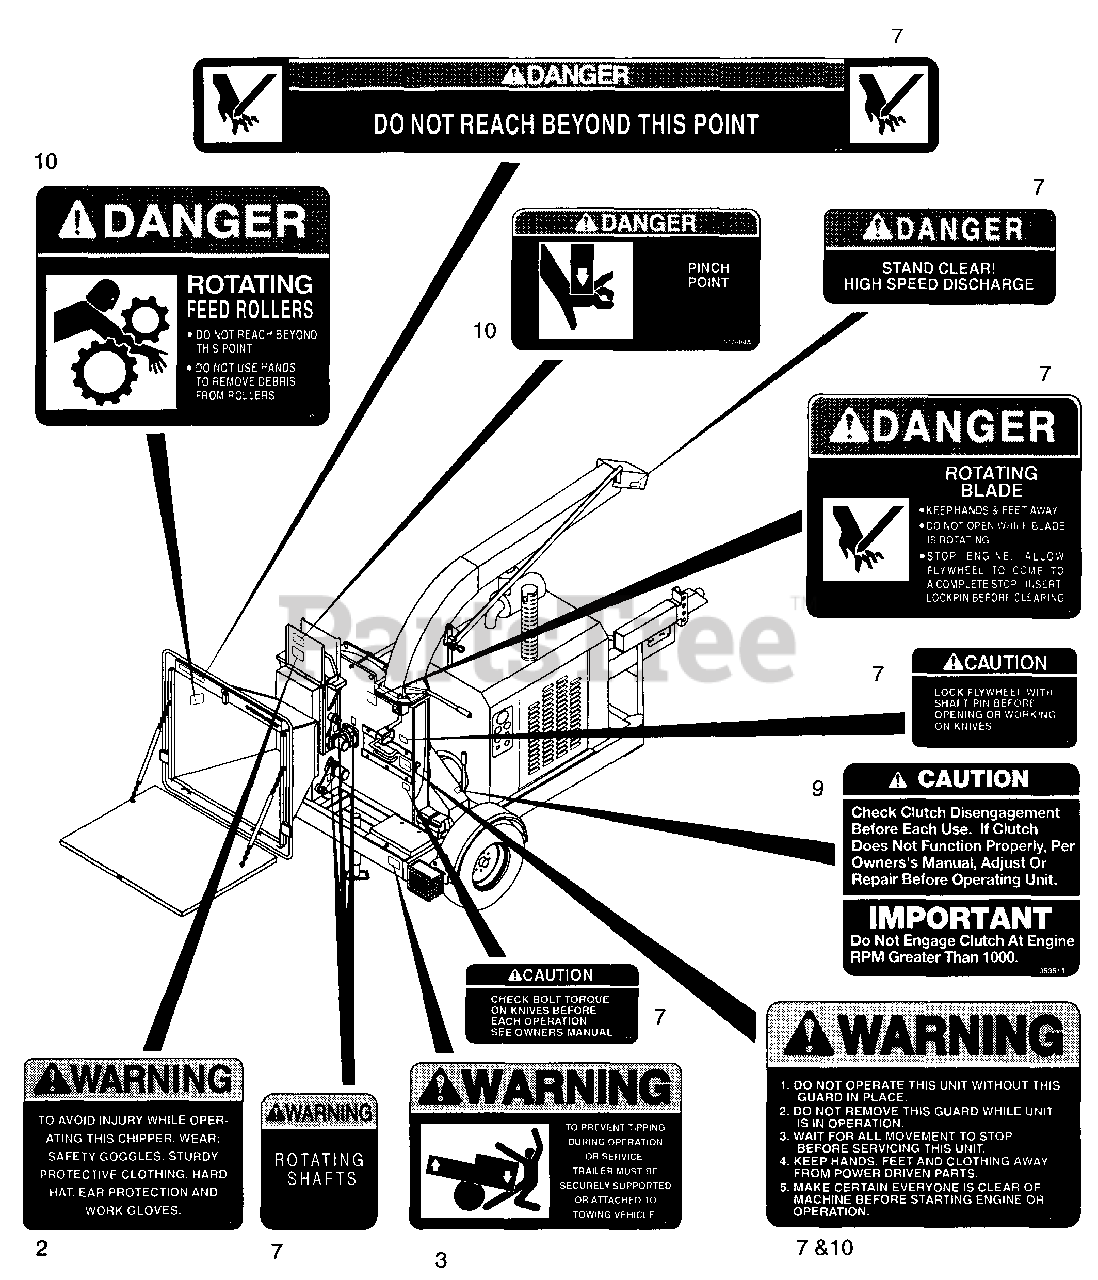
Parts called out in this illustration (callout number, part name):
2	Decal-WARNING Protective
3	Decal-WARNING-Tipping
7	Decal Set-Large Chippers
9	Decal-Clutching Instruction
10	Decal Set
